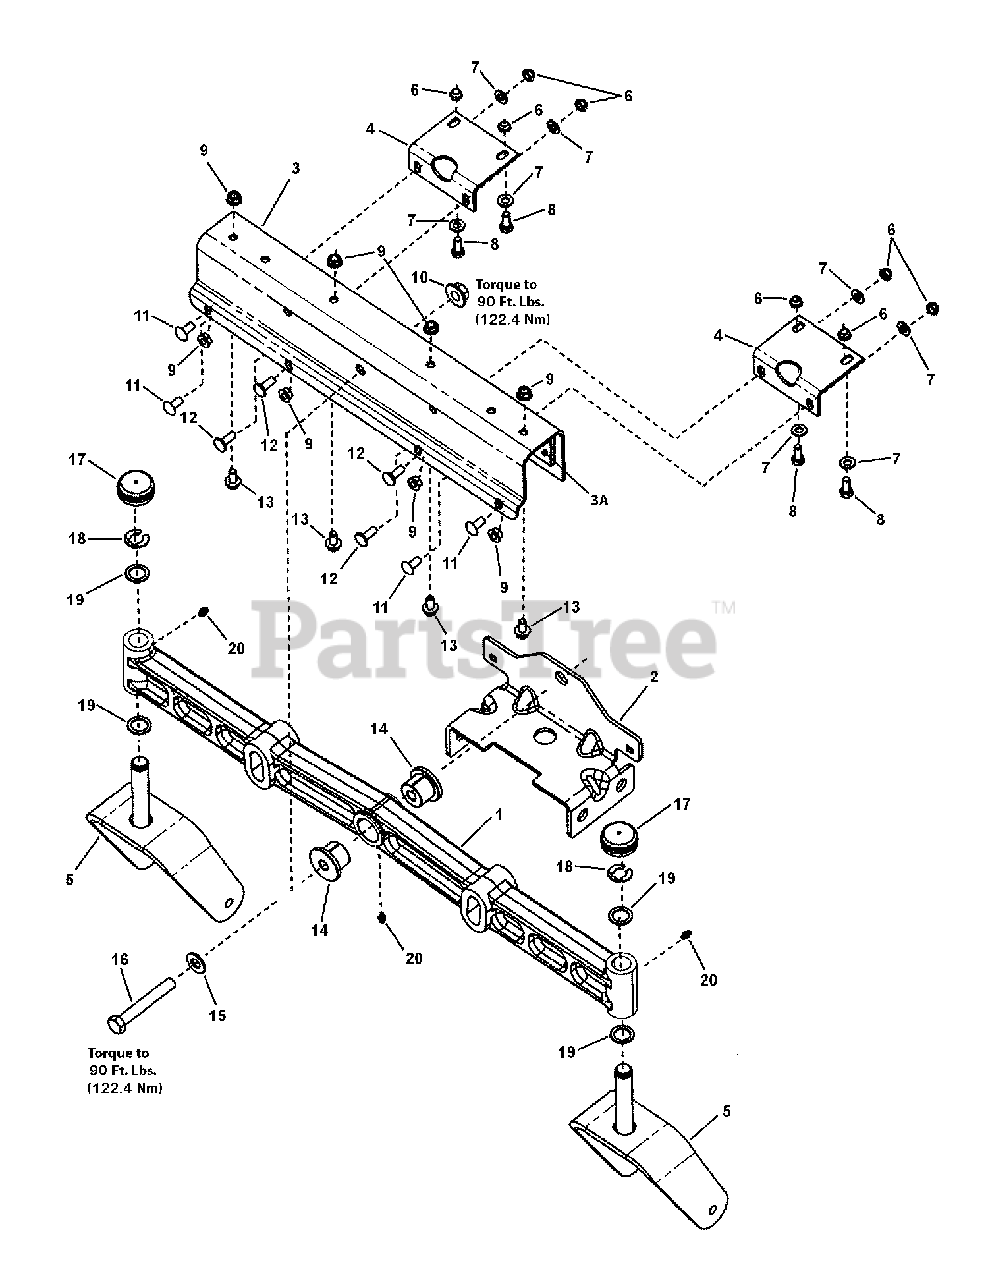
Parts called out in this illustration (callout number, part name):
1	AXLE, Front Iron Casting Machined ZT 2007
2	BRACKET, Hanger, Front (46/52)
3	BRACKET, Axle
3A	PLATE, Friction, Adhesive Backed
4	BRACKET, Axle Support
5	WELDMENT, Caster Yoke & Spindle, Black
6	NUT, 5/16-18 Hex Top Lock, GR B
7	WASHER, 5/16" Flat
8	SCREW, 5/16-18 x 3/4" Hex Head Cap, GR 5, YZ
9	NUT, 5/16-18 Flange Lock, YZ
10	NUT, 1/2-13 Hex Flange Two-Way Lock Black
11	BOLT, 5/16-18 x 3/4" Round Head Short Square Neck, GR 5, YZ
12	BOLT, 5/16-18 x 7/8" Round Head Short Square Neck, GR 5, Black
13	BOLT, 5/16-18 x 5/8" Hex Flange lock, GR 5, YZ
14	BUSHING, Axle Pivot
15	WASHER, 1/2" Flat (SAE)
16	SCREW, 1/2-13 x 3-1/2" Hex Head Cap, YZ
17	HUB CAP, 1.481 I.D x .62 Long Red Poly
18	RING, Klipring External for .750 Dia. Shaft Bln
19	WASHER, 0.750 ID x 1.60 OD x .05 Thick, Black
20	LUBE FITTING, 3/16" Press Fit
